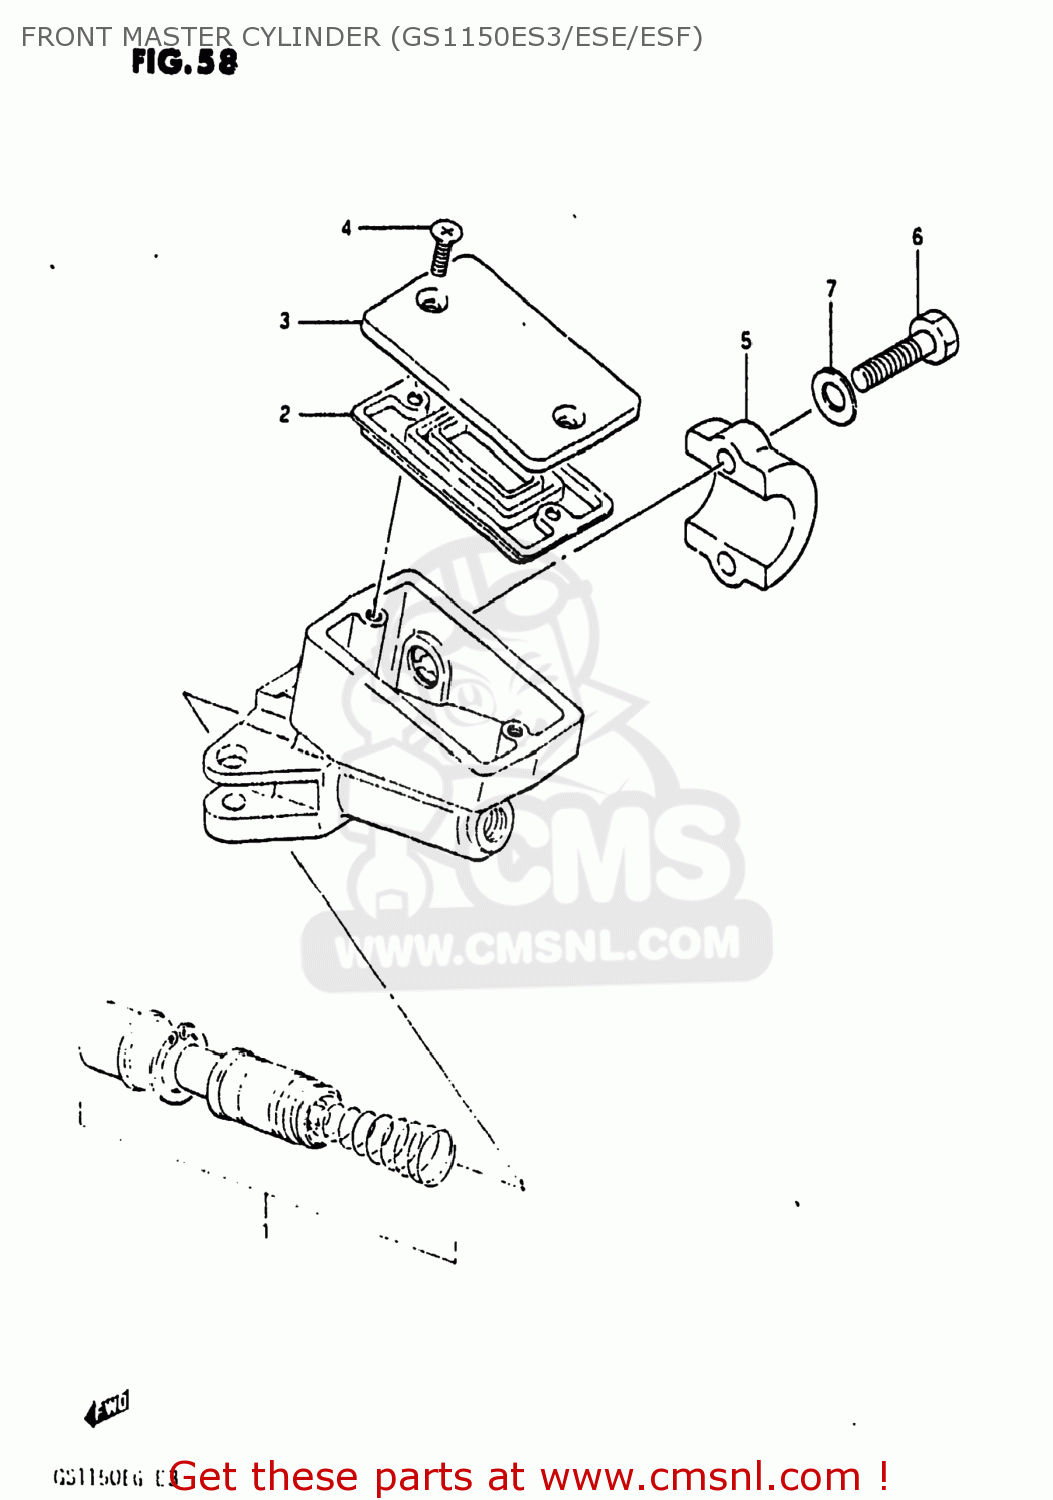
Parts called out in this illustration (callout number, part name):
1	PISTON & CUP SET
2	3
3	CAP
4	SCREW
5	HOLDER,MASTER CYLINDER
6	BOLT
7	WASHER
